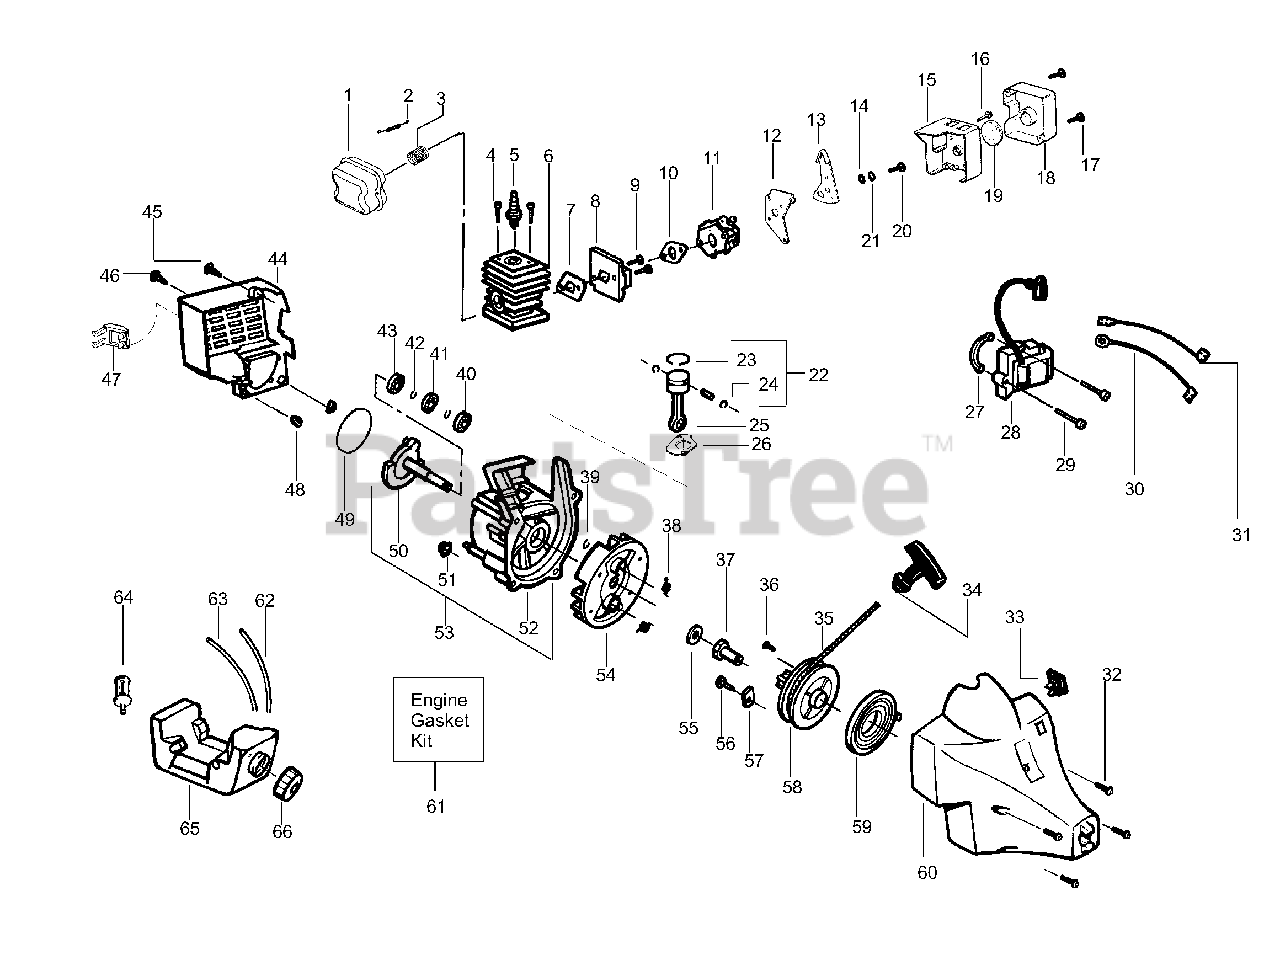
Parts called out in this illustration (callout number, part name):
1	Kit-Muffler
2	Muffler Spring
3	Kit-park Arrestor
4	Screw-Cylinder
5	Spark Plug (RCJ 8Y)
6	Cylinder Kit
7	Gasket-Cylind./Carb.
8	Carb. Adaptor Kit
10	Gasket-Carb.
11	Carburetor Ass'y Kit
12	Choke Plate Mounting
13	Choke Lever
18	Air Filter Cover
19	Air Filter Foam
21	Spacer-Choke
22	Piston Kit
23	Piston Ring
24	Piston Pin Retainer
25	Connecting Rod Ass'y.
26	Gasket-Cylinder
27	Spacer-Module
28	Ignition Module
30	Ground Wire Ass'y.
31	Lead Wire Ass'y.
32	Screw
33	On/Off Switch
34	Starter Handle
35	Rope Kit
37	Drive Coupling
38	Starter Dog Spring
39	Retainer Ring-C'shaft
40	Outer Bearing
41	C'case Seal
42	Retain. Ring-C'case
43	Inner Bearing
44	Rear Shroud
46	Screw
47	Guard-Muffler
48	Isolator-Shroud
49	O-Ring/Gasket-C'case
50	Crankshaft Ass'y.
51	Isolator-C'Case
52	Crankcase Ass'y.
53	C'case & C'shaft Assy.
54	Flywheel Ass'y.
55	Washer-Flat
57	Retainer-Can
58	Starter Pulley Kit
59	Starter Spring
60	Fan Housing Ass'y
61	Engine Gasket Kit
62	Fuel Line (Small)
63	Fuel Line (Large)
64	Fuel Pickup Ass'y.
65	Fuel Tank Ass'y
66	Fuel Cap Ass'y.
